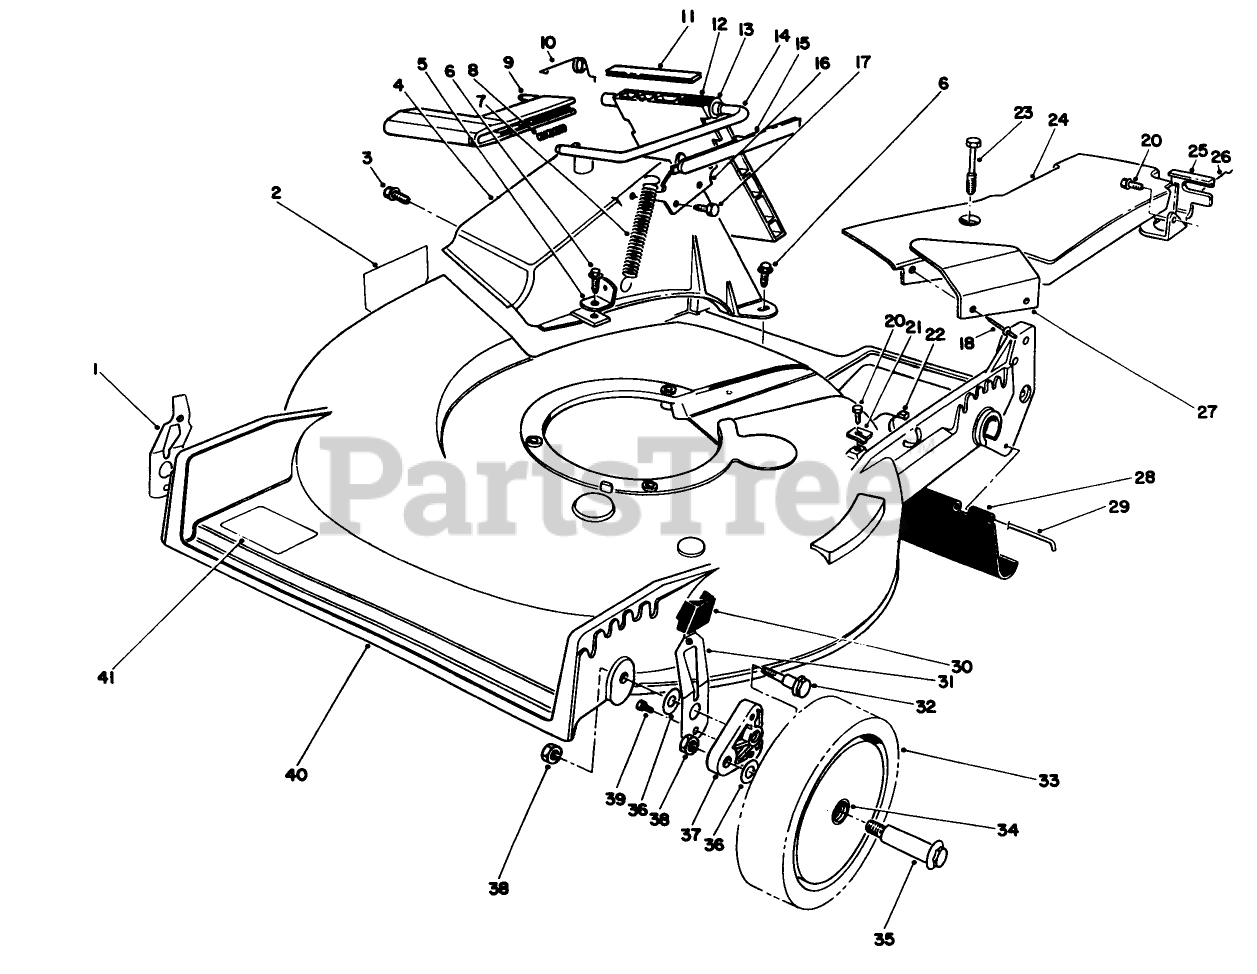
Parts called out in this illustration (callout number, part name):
1	RH SPRING ARM ASSEMBLY
2	DECAL-DANGER
3	SCREW AND WASHER ASM
4	DISCHARGE TUNNEL
6	SCREW-HWH
7	SPRING-DOOR
8	ORD.77-0200 ASM
9	ORD.77-0200 ASM
10	RETAINER-DOOR
11	ORD.77-0200 ASM
13	BUSHING-NYLON
14	ORD.77-0200 ASM
15	ORD.77-0200 ASM
16	DOOR LATCH PLATE
17	SCREW-PLASTITE
18	RIVET-HEAD, FLAT
20	SCREW-HWHTF
21	CLAMP-CABLE
22	TIE-CABLE
23	SCREW-HWH
26	RETAINER-CABLE
29	ROD-SHIELD
30	KNOB-ARM
31	LH SPRING ARM ASSEMBLY
32	SCREW-SHOULDER
34	BUSHING
35	WHEEL BOLT
36	WASHER
37	ARM-PIVOT, FRONT
39	SCREW-HWH
40	HOUSING W/DECAL
41	DECAL
